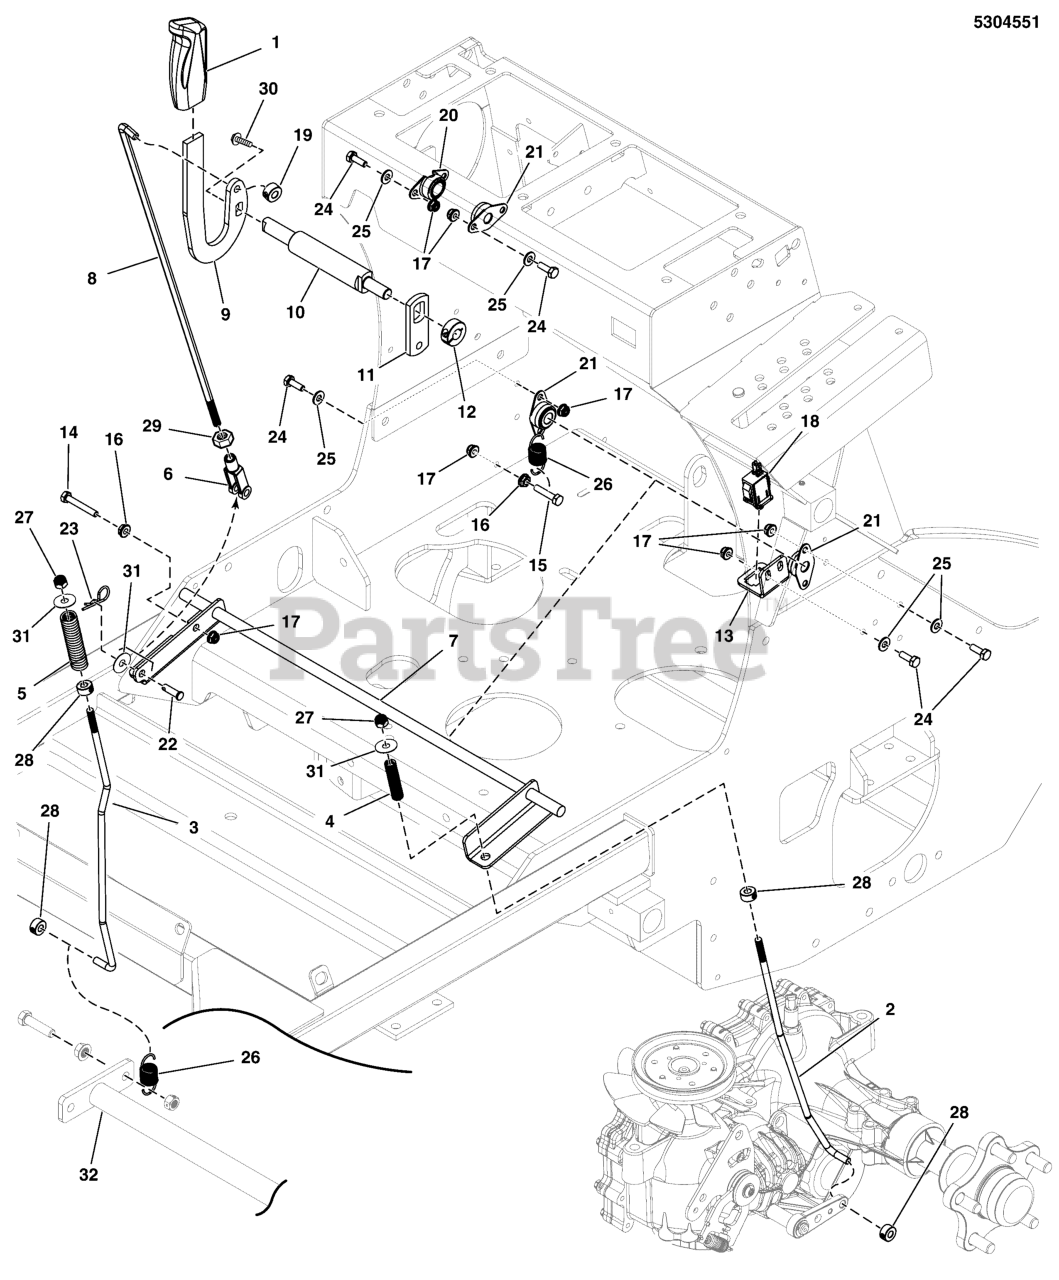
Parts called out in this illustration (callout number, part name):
1	GRIP, BLACK FLEXIBLE
2	ROD, BRAKE CTRL, LOWER - LH
3	ROD, BRAKE CTRL, LOWER - RH
4	SPRING-COMP, .375IDX2.75LGX.054WR, SS
5	SPRING-COMP, .496ID X 3.00LG X .112WR
6	CLEVIS, 5/16-24, STEEL, CLEAR ZINC
7	WELD, BRAKE SHAFT PIVOT - BLK
8	ROD, BRAKE, STAND-ON
9	PLATE, BRAKE LEVER, SRSZ - BLK
10	SHAFT, UPPERBRAKE ROD SHORT, SRSZ1
11	PLATE, BRAKE TAB, STAND-ON
12	COLLAR, 1/2 SET (1/2 SPLIT COLLAR IN MODEL)
13	PLATE, PARKING BRAKE SWITCH - BLK
14	BOLT, 1/4-20 X 1-1/2 GD5 CZ
15	BOLT, 1/4-20 X 1-1/4 GD5 CZ
16	NUT, 1/4-20 HEX SERR. FLANGE
17	NUT, 1/4-20 Hex Nylock Flange
18	SEE ELECTRICAL GROUP
19	COLLAR, 5/16" Set
20	BEARING, 5/8" FLANGED, PLASTIC BALL
21	BEARING, 1/2 FLANGED, PLASTIC BALL
22	PIN, CLEVIS, 5/16 X 1, PLATED
23	PIN, HAIR, .0585 X 1-1/8, 1/4 EYE, YZ
24	BOLT, 1/4"-20 X 3/4" GD5 YZ
25	WASHER, 1/4 SAE
26	SPRING-EXT, .740 ODX2.025LGX.072WR, BLK
27	NUT, 5/16-24 HEX NYLON LOCK
28	COLLAR, DOUBLE SPLIT, 7MM
29	NUT, Hex, 5/16-24
30	SCREW-HEX SEMS WSHR 1/4-20 X.88 DOG PT
31	WASHER, 5/16" USS
32	SEE MAIN FRAME GROUP
